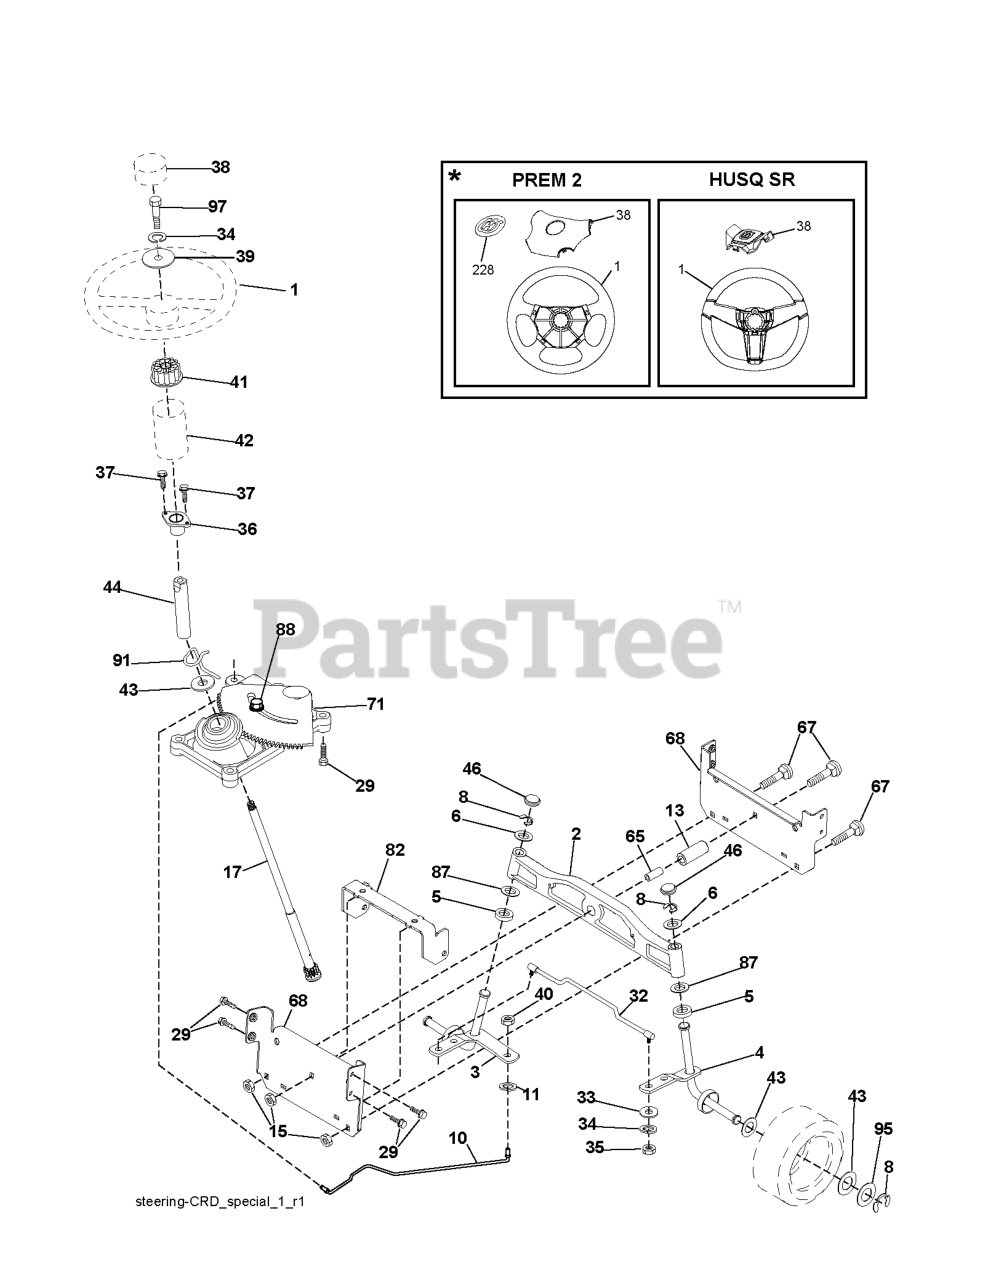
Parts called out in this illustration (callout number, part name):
1	RP WHEEL.STEER.HUSQ.PREM.OVMLD
2	AXLE ASSY FRONT
3	SPINDLE.ASM.LH.15"TIRES
4	SPINDLE.ASM.RH.15"TIRES
5	THRUST WASHER
10	DRAGLINK.15".TIRES.2001
11	WASHER, LOCK 3/8
13	TUBE, PIVOT AXLE
15	NUT
17	SHAFT STEERING SPLINE
29	SCREW, 3/8-16X3/4
33	WASHER M
34	WASHER.LOCK.HVY.HLCL.SPR.5/16
35	NUT, CROWNLOCK
36	BUSHING, STEERING
37	SCREW.TT.#10-32X.5.3/8.FLANGE
38	RP INSERT.CAP.WHL.STRG.HUSQ.
39	WASHER.11/32
40	NUT CROWNLOCK 3/8-24
41	ADAPTER, WHEEL STNG..
42	BOOT, STEERING
44	SHAFT.EXTEN.STRG.SPLINE
46	CAP.SPINDLE.BLACK
65	SPACER BRACE AXLE
67	BOLT CARRIAGE
68	BRACE.AXLE.15"TIRES
71	STEERING ASM
82	BRACKET.SUSP.CHASSIS.FRONT.15
87	WASHER, FLAT .781 X 1 1/2"
88	BOLT, SHOULDER 7/16-20
91	CLIP.STEERING
95	WASHER.HARDENED
228	DECAL.WHEEL.STRG.LGN.H
